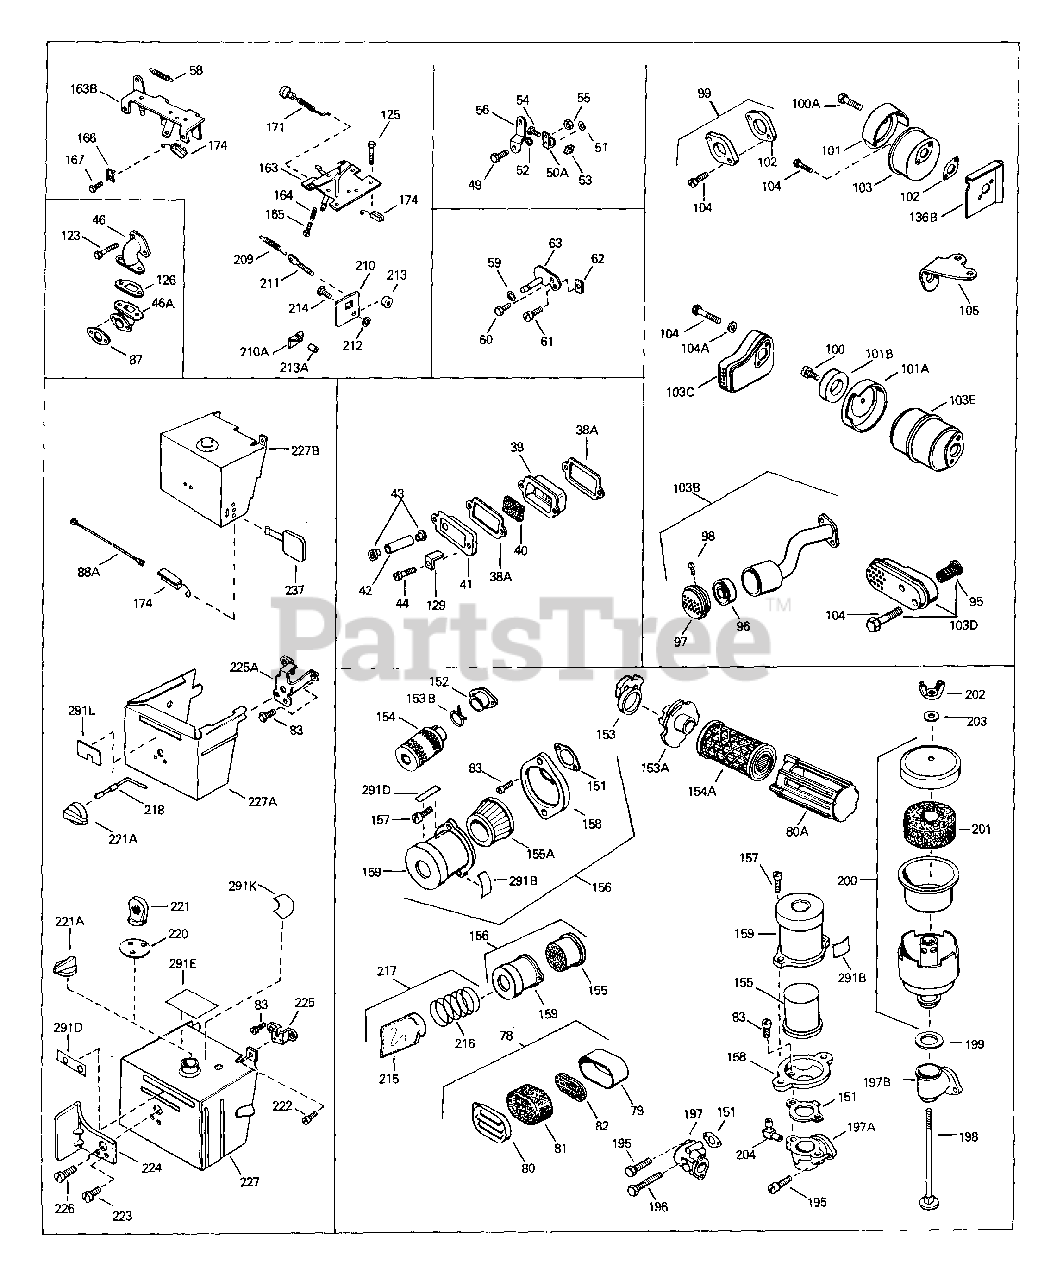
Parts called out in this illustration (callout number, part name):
40	Element, Breather
44	Screw, Fil. hd. Sems, 10-24 x 1/2
49	Screw, Hex washer hd., 8-32 x 5/16
56	Lever, Governor
58	Spring, Extension
59	Washer, Flat
78	Cleaner Assy., Air
83	Screw, Fil. hd. Sems, 10-32 x 1/2
87	Gasket, Carburetor (1/32" thick)
96	Screen, Muffler
97	Cover, Muffler
98	Screw, Hex hd. Self tap, 8-18 x 3/8
99	Kit, Exhaust adapter
102	Gasket, Exhaust
103B	Muffler
104	Screw, Hex washer hd. Durlok, 1/4-20 x 5/8
105	Bracket, Muffler
151	Gasket
155A	Element, Air cleaner (Paper)
156	Cleaner Assy., Air (Poly)
156	Cleaner Assy., Air (Paper)
157	Screw, Fil. hd. Sems, 8-32 x 3/8
158	Bracket, Air cleaner
159	Body, Air cleaner
163	Control Assy., Speed
164	Spring, Compression
165	Screw, Fil. hd., 5-40 x 7/16
166	Clip, Conduit
167	Screw, Hex washer hd. Sems, 10-32 x 3 /8
174	Terminal Assy.
215	Bag, Pre-cleaner
216	Spring, Pre-cleaner bag
217	Kit, Pre-cleaner
